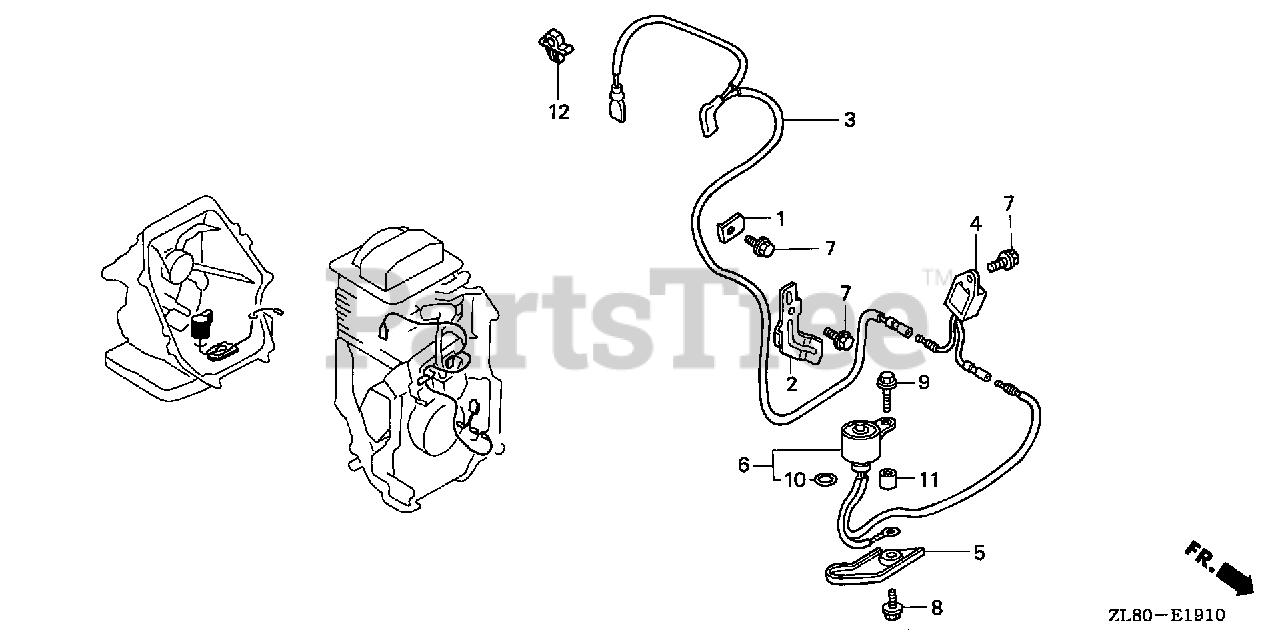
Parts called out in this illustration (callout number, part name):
1	CLAMP, STOP SWITCH WIRE
2	CLAMP, WIRE
3	WIRE, STOP SWITCH
4	ALERT UNIT, OIL
5	PROTECTOR, SWITCH
6	SWITCH, OIL LEVEL
7	BOLT, FLANGE (6X12) (CT200)
8	BOLT, FLANGE (6X14) (CT200)
9	BOLT, FLANGE (6X28) (CT200)
10	O-RING (11.8X2.4)
11	COLLAR (6.6X13.8X14.5)
12	HOLDER, STOP SWITCH WIRE
